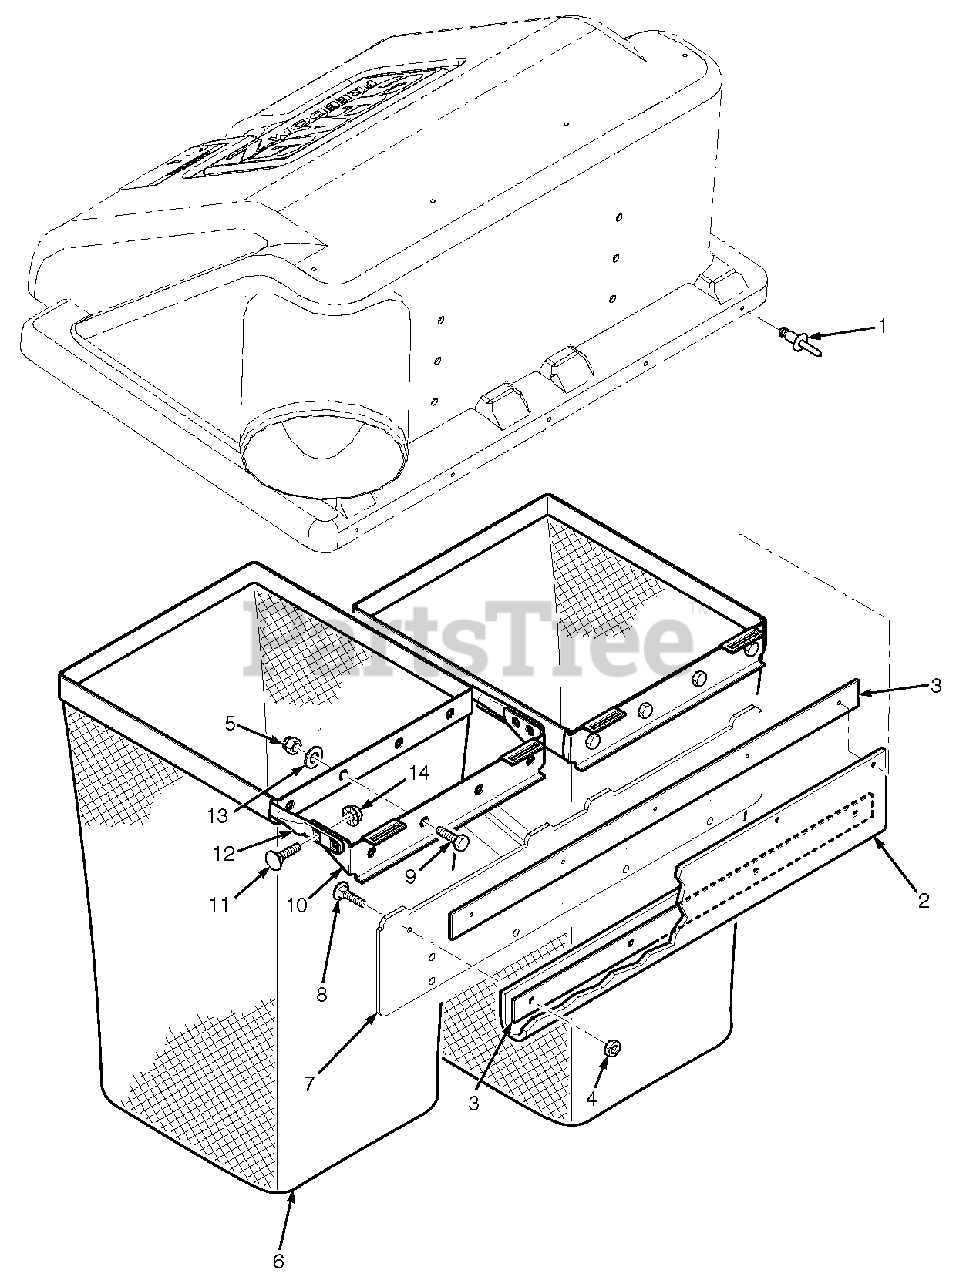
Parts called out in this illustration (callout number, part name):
1	Bolt, Carriage 5/16-18 x 3/4"
2	Baffle, LH - 48" Deck
2	Baffle, LH - 52" Deck
2	Baffle, LH - 61" Deck
3	Cutter Blade, High Lift (36" Deck)
3	Cutter Blade, High Lift (48" Deck)
3	Cutter Blade, High Lift (52" Deck)
3	Cutter Blade, High Lift (61" Deck)
4	Bolt, Carriage 3/8-16 x 1"
5	Nut, Elastic Stop 3/8-16
6	Flatwasher, 3/8-.438 x 1.00 x .083
7	Baffle Weldment,RH - 36" Deck
7	Baffle Weldment, RH - 48" Deck
7	Baffle Weldment, RH - 52" Deck
7	Baffle, Weldment, RH - 61" Deck
8	Flatwasher, 5/16-.344 x .688 x .065
9	Nut, Center Lock 5/16-18
10	Weight Assembly
11	Flatwasher, 1/2-.562 x 1.375 x .109
12	Bolt, Hex Head 1/2-13 x 1-1/4"
13	Support Weldment, Weight Mounting
14	Nut, Serrated Flange 1/2-13
15	Cutter Blade, Cross - 36" & 52" Deck
15	Cutter Blade, Cross - 48" Deck
15	Cutter Blade, Cross - 61" Deck
16	Pin, Weight Retention
